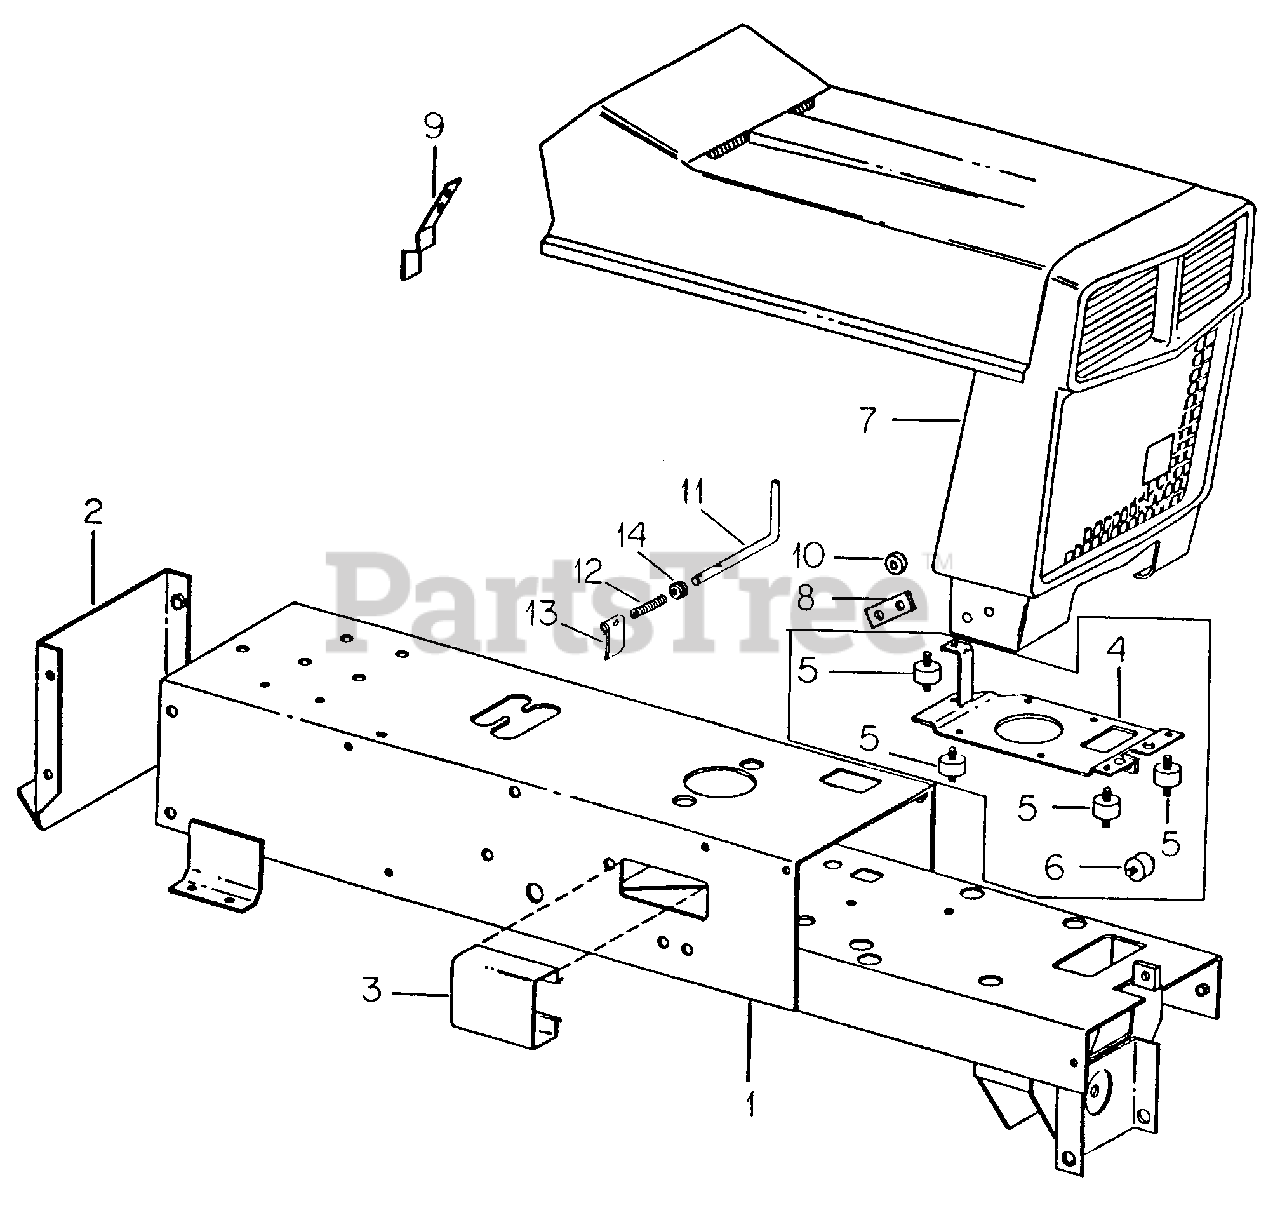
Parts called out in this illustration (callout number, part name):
1	Frame Assy
2	Drawbar Assy
3	Cover, Steering Arm
4	Plate Assy, Engine Mounting
5	Mount, Cylindrical
6	Mount, Engine Front
7	Hood Assy
8	Bracket, Hood Front Mounting
9	Latch, Hood
10	Spacer, Rubber
11	Rod, Dump Valve
12	Spring, Dump Valve
13	Lever, Dump
14	Grommet, Rubber
